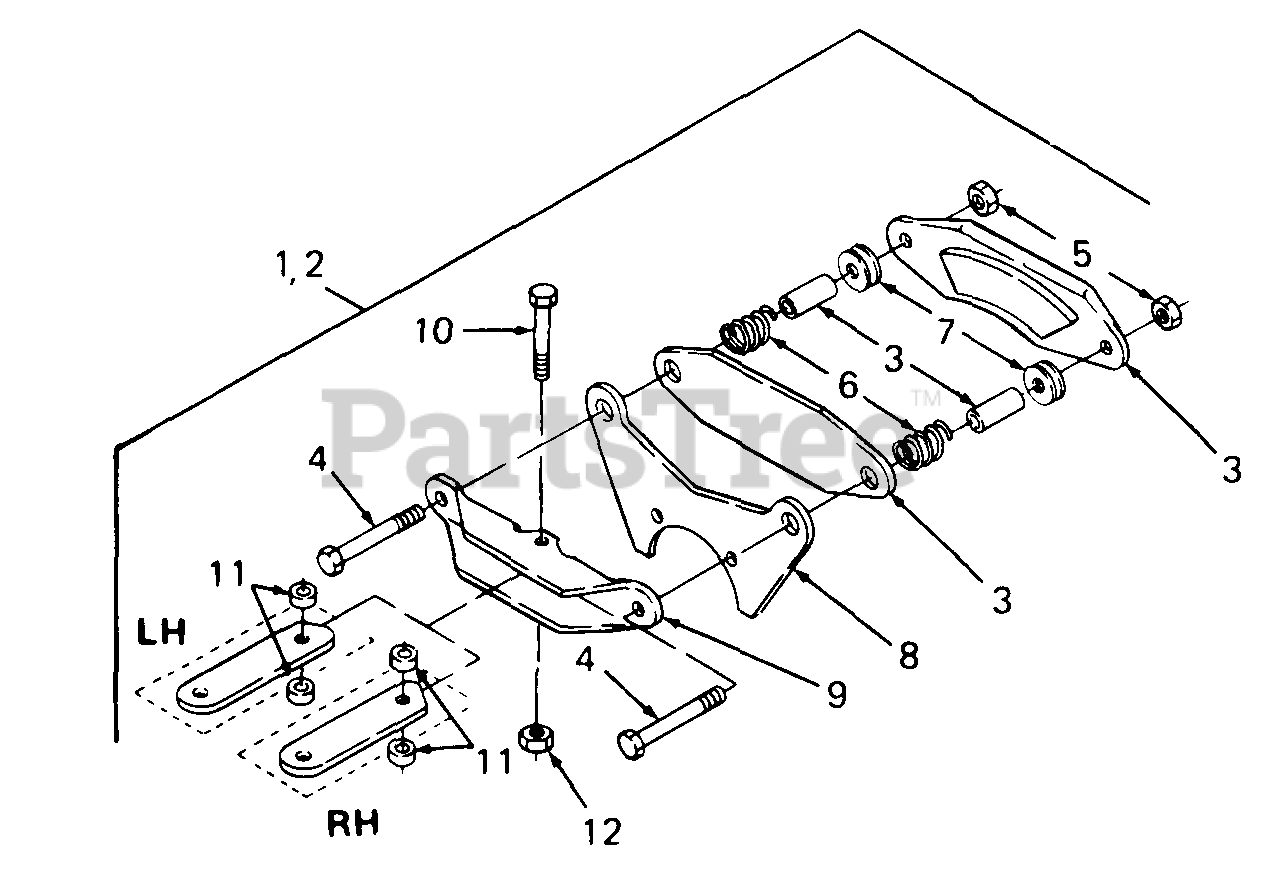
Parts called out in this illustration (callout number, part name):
1	Brake Kit, RH Caliper
2	Brake Kit, LH Caliper
3	Puck Kit, Brake
4	Screw, Hex Cap, 3/8-24 x 2.50 Lg GR5
5	Nut, Hex Lock, 3/8-24 GR5
6	Spring, Compression
7	Washer, Flat, .390 x 1.0 x .030 Thk HDN
8	Bracket, Brake Mounting
9	Bracket Assy, Actuator
10	Screw, Shoulder
12	Nut, Hex Top Lock, 1/4-20
